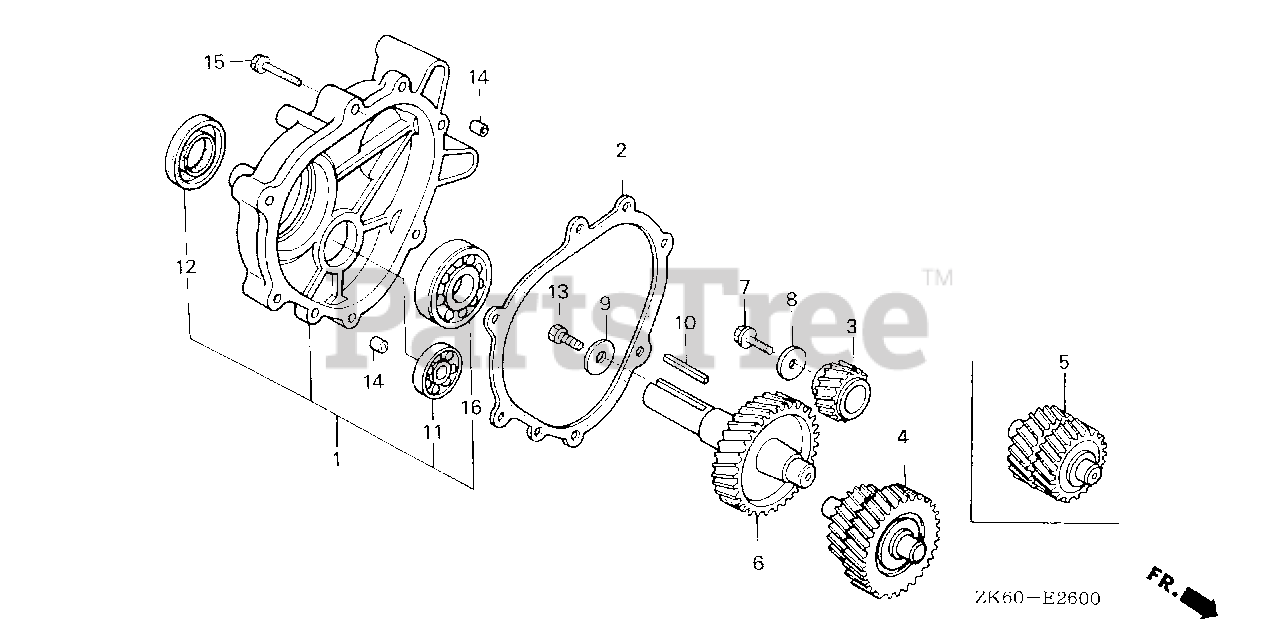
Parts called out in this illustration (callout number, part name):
1	COVER ASSY., GEAR CASE
2	GASKET, CHAIN CASE COVER
3	GEAR, PRIMARY DRIVE (22T)
4	COUNTERSHAFT (21T/27T)
6	SHAFT, P.T.O. (33T)
7	BOLT, FLANGE (8X25)
8	WASHER (8.5X42X4.5)
10	KEY (7X7X33) (OVER SIZE) (YELLOW)
11	BEARING, RADIAL BALL (6202) (NTN)
12	OIL SEAL (30X46X8)
14	PIN, DOWEL (8X14)
15	BOLT, FLANGE (8X40)
16	BEARING, RADIAL BALL (6206)
